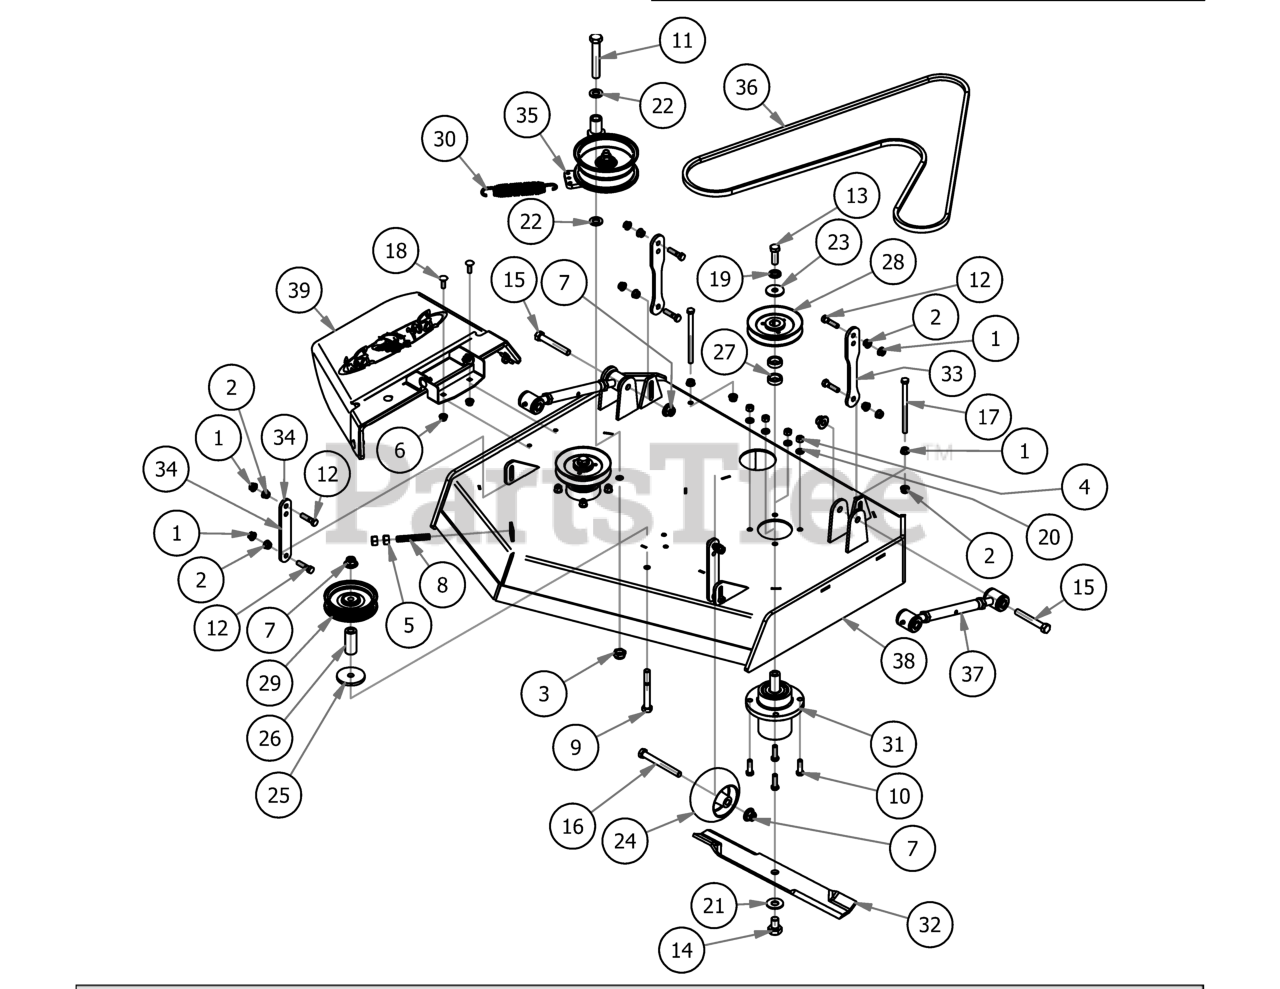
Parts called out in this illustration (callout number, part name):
1	3/8" Flange Nut
2	3/8" Nylock Flange Nut
3	5/8-11 Nylon Insert Jam Half Nut
4	3/8" Hex Nut
5	1/2" Hex Nut
6	5/16" Nylock Flange Nut Zinc
7	1/2-13 NYLON INSERT FLANGE LOCKNUT ZINC
8	All Thread-Pump Idler Tensioner
9	1/2" x 4" Bolt (Grade 8)
10	3/8" x 1 1/4" Hex Bolt
11	5/8" x 4" Hex Bolt
12	3/8" x 1 1/2" Hex Bolt
13	1/2"-20 x 1 1/2 - Grade 5 Fine Thread Bolt
14	5/8" x 1 1/2" Grade 8 Hex Bolt (Fine)
15	1/2-13 x 3 1/2 GR 5 Hex Bolt
16	1/2" x 4 1/2" Bolt
17	3/8-16 x 5 1/2 Hex Bolt
18	5/16" x 1" Carriage Bolt
19	1/2" Lock Washer Zinc
20	3/8" Lock Washer
21	5/8'' Flat Washer
22	.630 ID Plastic Washer
23	1/2 Belleville Washer
24	2019 Deck Wheel
25	MZ Deck Idler Spacer
26	2019 Revolt Stationary Idle Spacer
27	36 Deck Spindle Spacer
28	MZ Deck Pulley
29	5 V Idler Pulley 1/2" Bore
30	2009 Deck/Pump Idler Spring
31	36'' Revolt Spindle Assembly
32	52" Deck Fusion Blade
33	2019 Stand-On Rear Deck Hanger
34	2019 Stand on deck hanger_front
35	2020 36" Revolt Deck Idler Assembly
36	2020 Walk-Behind 36 Deck Belt
37	2018 Maverick Turnbuckle (Top Link)
38	2020 36 Stand On Deck Weldment
39	2020 36 Stand On Discharge Assembly
